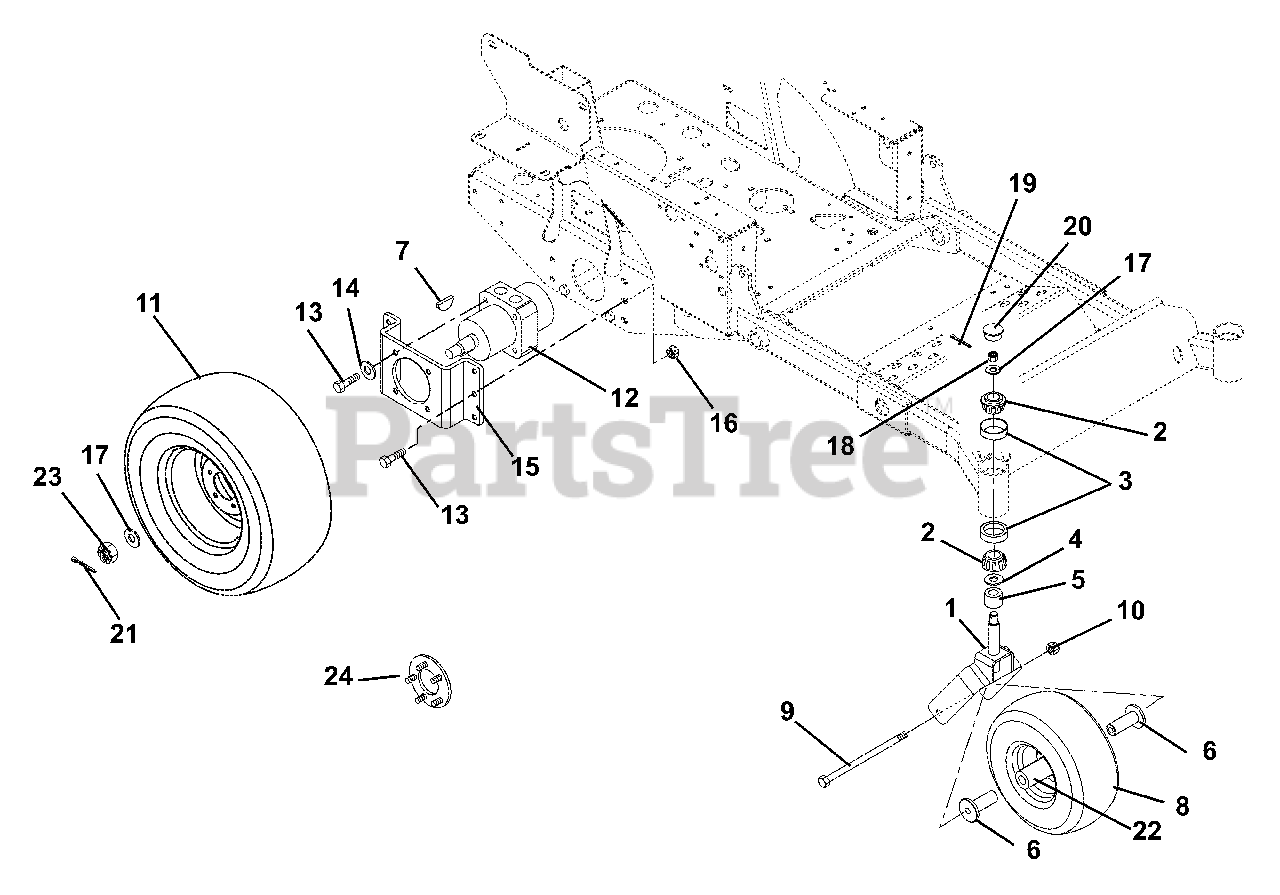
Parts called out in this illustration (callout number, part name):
1	Weldment, Front Fork
2	Bearing, Cone with Grease, 1.0 x .58
3	Bearing, Cup 1.980 x .420
4	Bearing Seal 1.5 x 2 x .18
5	Spacer, PM, 1.03 I.D. x 1.5 O.D. x .375
6	Spacer, Wheel
7	Key, Woodruff .31 x 1.00
8	Wheel/Tire Assembly 5.25 x 13.00
9	Bolt, Hex .50-13 x 7.50 Grade 5
10	Nut, Locking Top Flange .50-13
11	Wheel, Tire Assembly 7.00 x 21.00 (056, 314)
11	Wheel, Tire Assembly 20 x 10-10 (065)
11	Tire, 20 x 10.00-NHS Turf Saver (065)
11	Tire, 20 x 10.00 Multi Trac C-S (065)
11	Tire, 21 x 7.00 Turf Saver (056, 314)
12	Motor, Hydraulic Wheel
13	Bolt, Hex .38-16 x 1.00 Grade 5
14	Washer, Locking .38 x .094 Regular
15	Bracket, Wheel Motor
16	Nut, Locking Top Flange .38-16
17	Washer, Flat Steel .755 x 1.375 x .062
18	Nut, Slotted .75-16
19	Pin, Cotter .16 x 1.00
20	Cap, Dust
21	Pin-Cotter .09 x 1.25 Extended Prong Square Cut
22	Bearing, 25MM I.D. x 52MM OD x 15MM
23	Nut, Hex .75-20
24	Assembly, Service Hub with Studs
